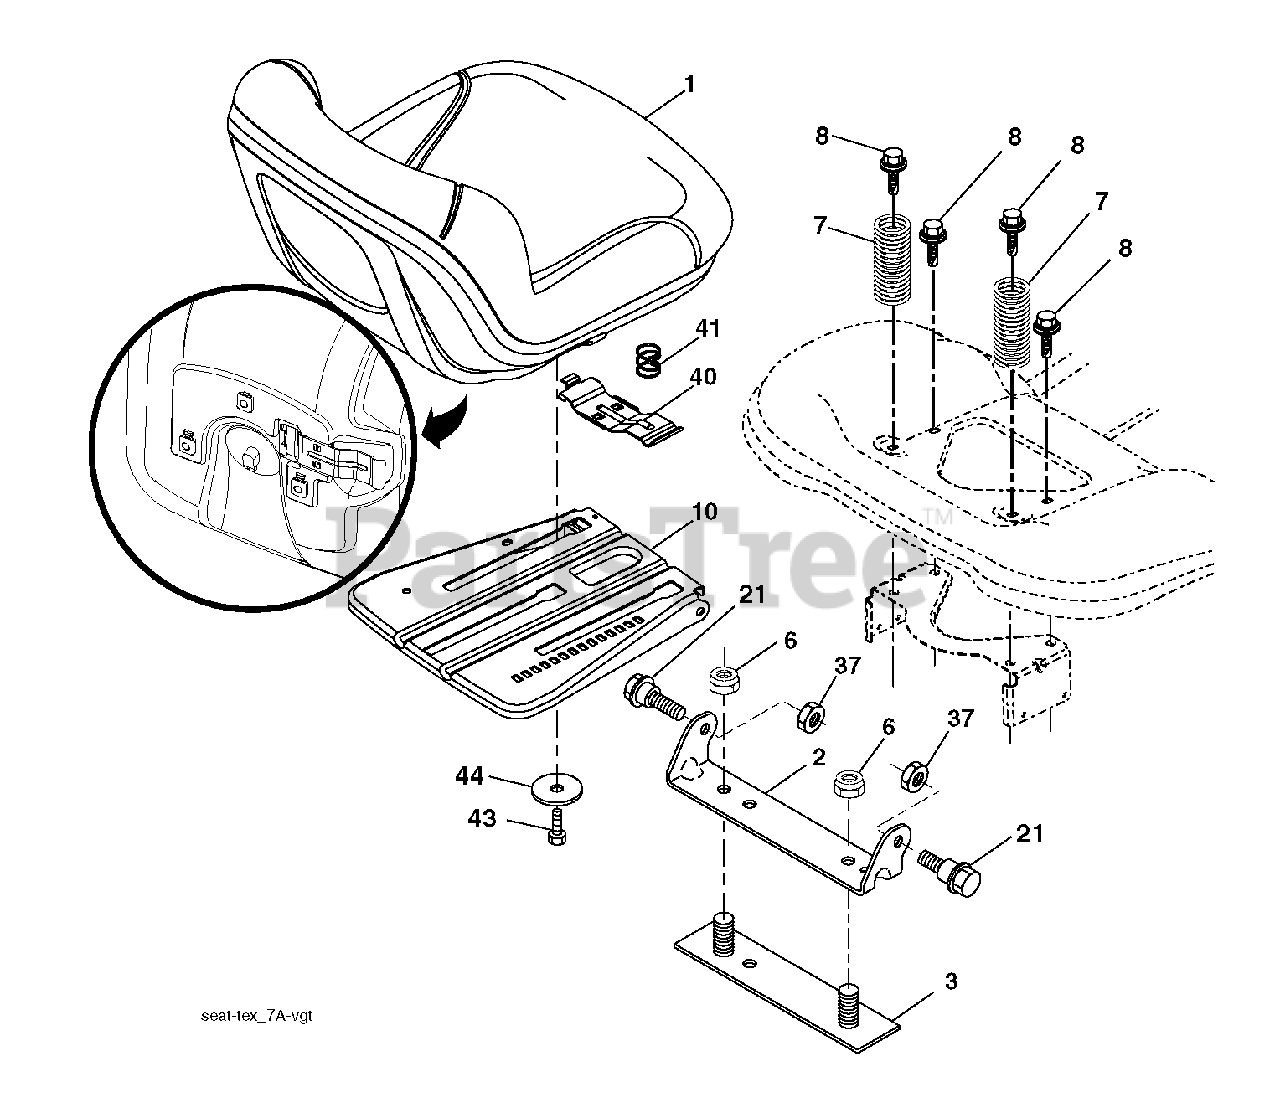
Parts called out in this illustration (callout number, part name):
1	SEAT.TH150.MS498.GRY.HUSQ.TEX
2	BRKT.PIVOT.FENDER
3	STRAP
6	NUT
7	SPRING.COMPRESSION.SEAT.BLACK
8	BOLT, 5/16-18 X 1 3/4
10	PAN.ASM.SEAT.3PT
21	BOLT.SHOULDER.5/16-18
37	NUT.71038.31-18.HEX.NYLOCK
40	HANDLE.SLIDE.SEAT.TEX.GREY
41	SPRING.LATCH.SEAT.TEX
44	WASHER 13/32 X 2-3/8 X 12GA
